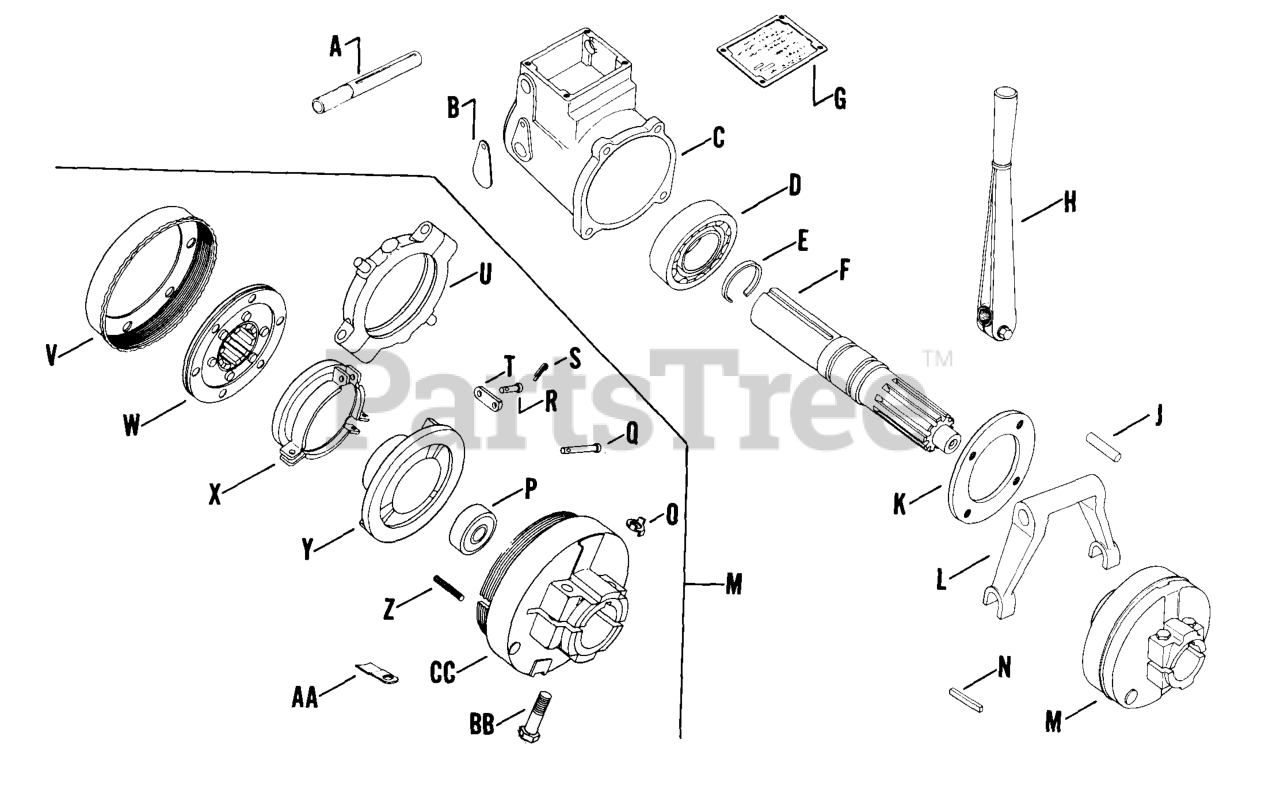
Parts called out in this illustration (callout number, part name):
A	SHAFT - DISCONTINUED
D	BEARING - DISCONTINUED
E	SNAP RING - DISCONTINUED
F	SHAFT - DISCONTINUED
H	LEVER - DISCONTINUED
K	PLATE - DISCONTINUED
L	YOKE - USE 24 471 01
O	LOCK - DISCONTINUED
P	Bearing
Q	PIN - DISCONTINUED
T	LINK - DISCONTINUED
U	BEARING - DISCONTINUED
X	SLEEVE - DISCONTINUED
Y	PLATE - DISCONTINUED
Z	SPRING - DISCONTINUED
